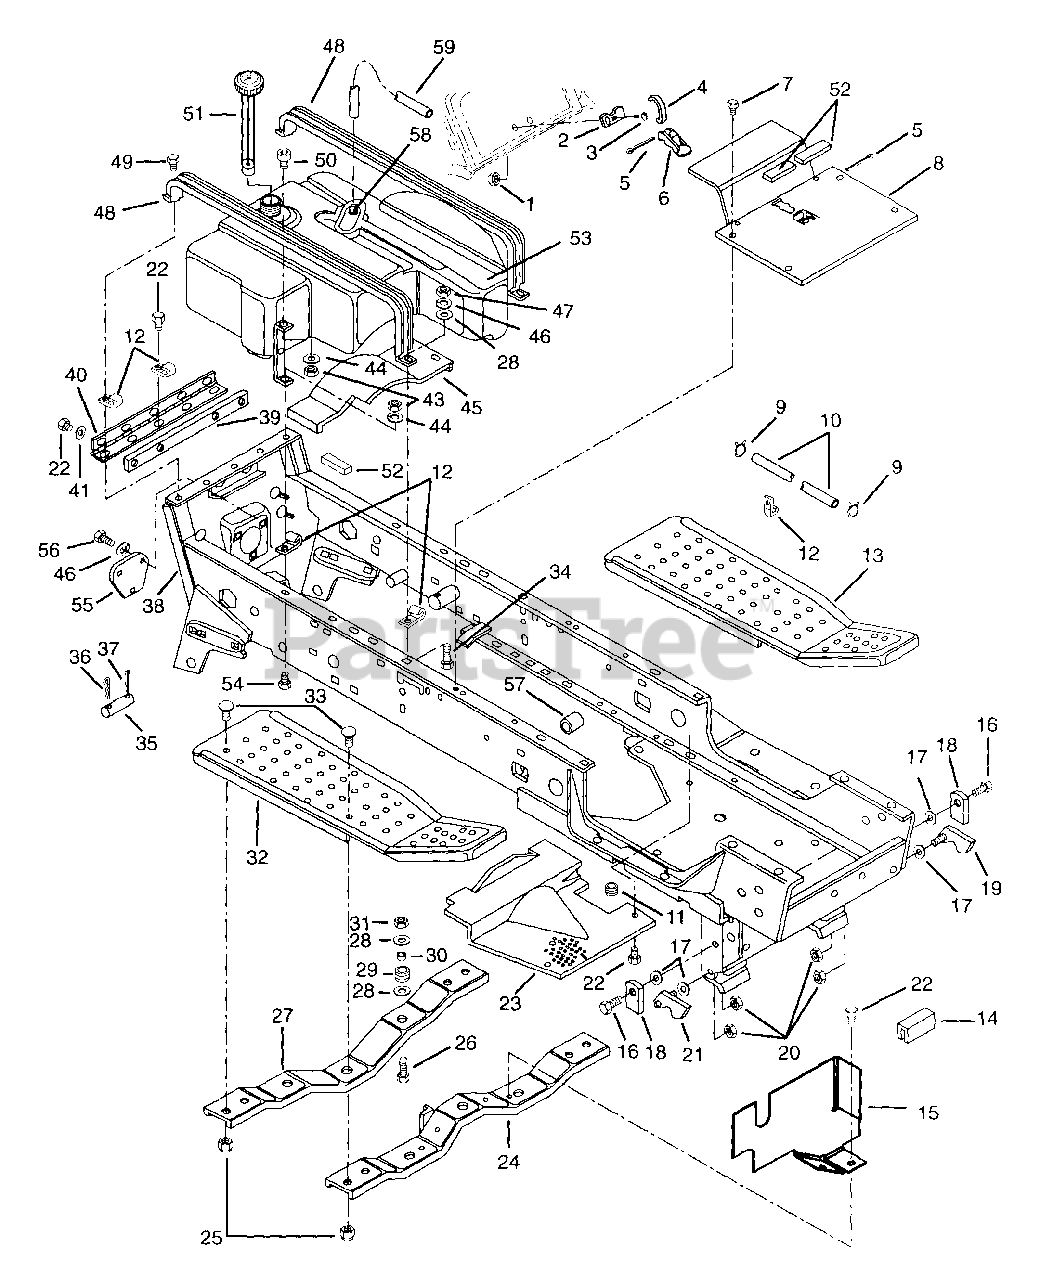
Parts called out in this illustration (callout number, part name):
1	NUT-LK DUAL FACE 10-24 PL
3	SCR-MCH 10-24X.50 SLRH PL
4	SPRING - DECK LATCH
5	PIN-COTR .12 X 1.25 PL
6	LEVER - DECK LATCH
7	SCR-TAP .250-20X.37 HWH PL TR
8	PLATE - FLOOR
9	CLAMP-HOSE WIR.490/.510X.092#8
10	FUEL LINE 1/4 X 67"
11	HOLE PLUG 1.375
12	J-CLAMP
13	L.H. RUNNING BOARD
16	BLT-HEX .38-16X1.00 PL
17	SPRING WASHER
18	LOCK STOP
19	LATCH LH
20	NUT-LK TOP .375-16 GR C YWZC
21	LATCH RH
22	SCR-TAP .312-18X.50 HWH PL TR
24	FRONT CHANNEL
25	NUT-FLG. .312-18 PL
26	BLT-HEX .31-18X1.25 PL GR2
27	REAR CHANNEL
28	WSHR-FL-STL .38X.875X.083 PL
29	GROMMET .438ID X .688 OD
30	SPACER .318X.430X.375
31	NUT-LK .312-18 GR A PL
32	R.H. RUNNING BOARD
33	BLT-RDHDSQSHNK .31-18X.50 YZ
34	BLT-RDHDSQNK .31-18X.75 SHT PL
36	PIN-HAIR INT .14X.4X2.75
37	PIN-COTR .12X1.0 PL
38	MAIN FRAME
40	HINGE-2" X 12.88 YWZC
41	WSHR-FL-STL .38X.875X.083 PL
42	SUPPORT
43	NUT-HEX .250-20 PL
44	WSHR-LK .250X.077 HVY PL
46	WSHR-LK .312X.097 PL HVY
47	NUT-HEX .312-18
48	CHANNEL
49	SCR-TAP .312-18X.75 HWH PL TR
50	SCR-SKH .25-20X.75 TSPH PL
51	GAS GAUGE & CAP
52	FOAM TAPE
53	GAS TANK ASSEMBLY
54	BLT-RDHDSQNK .25-20X.75
56	BLT-HEX .31-18X.75 PL GR2
57	BSHG-SLV .750X.814X .750 BRZ
58	FITTING - GAS TANK
59	GAS TANK FUEL LINE
